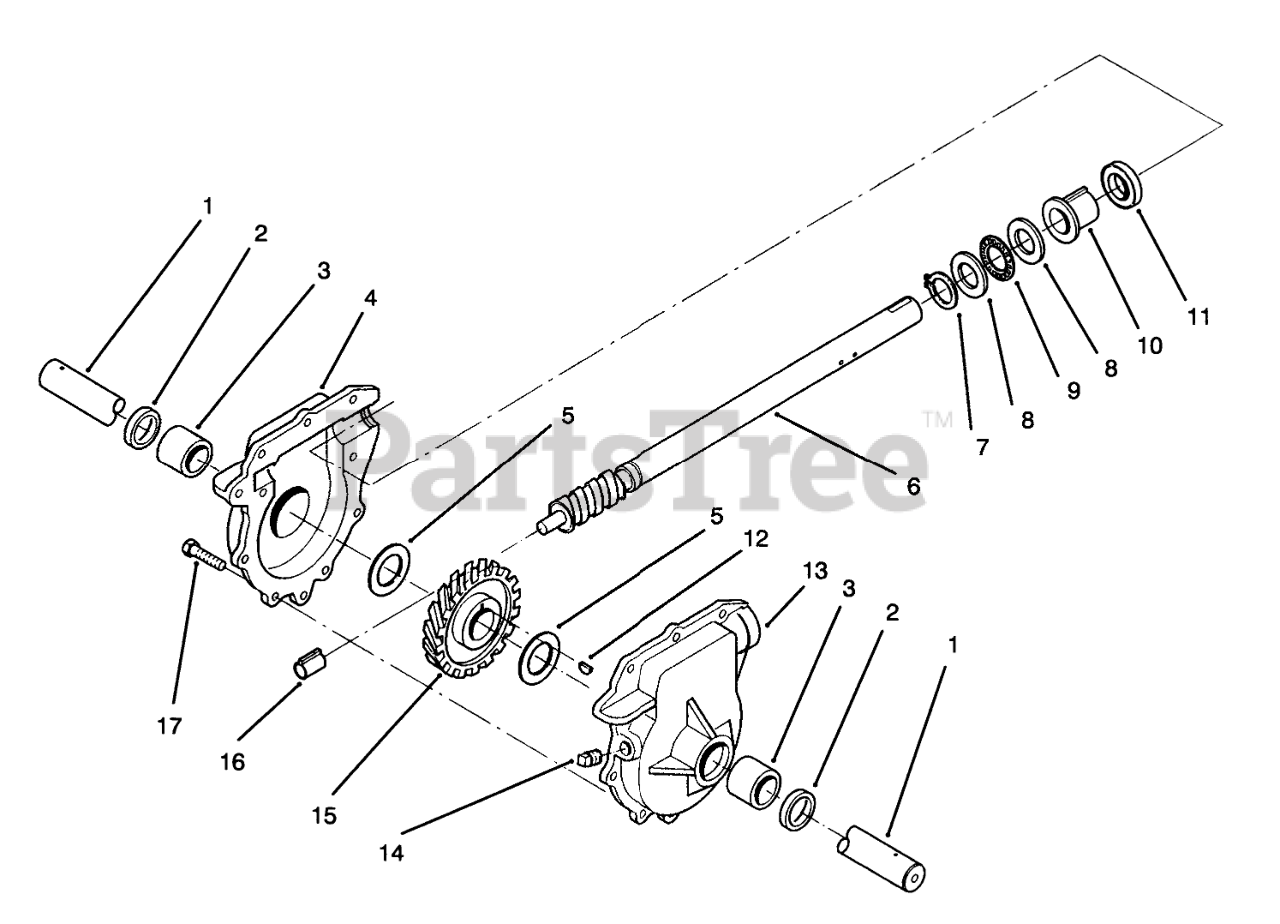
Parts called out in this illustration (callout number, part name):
1	SHAFT-AUGER
2	SEAL-OIL
3	BUSHING
4	Gearcase Assembly-R.H. (Incl. Ref. #2-3)
5	WASHER-THRUST
6	SHAFT-IMPELLER
7	RING-RETAINING, Ext
8	WASHER-THRUST
9	BEARING-THRUST
10	BUSHING-INPUT
11	SEAL-OIL
12	KEY-WOODRUFF
13	Gearcase Assembly-L.H.(Incl. Ref. #2-3)
14	PLUG-PIPE, SQH
15	GEAR-HELICAL
16	BUSHING-WORM
17	SCREW-HWH
